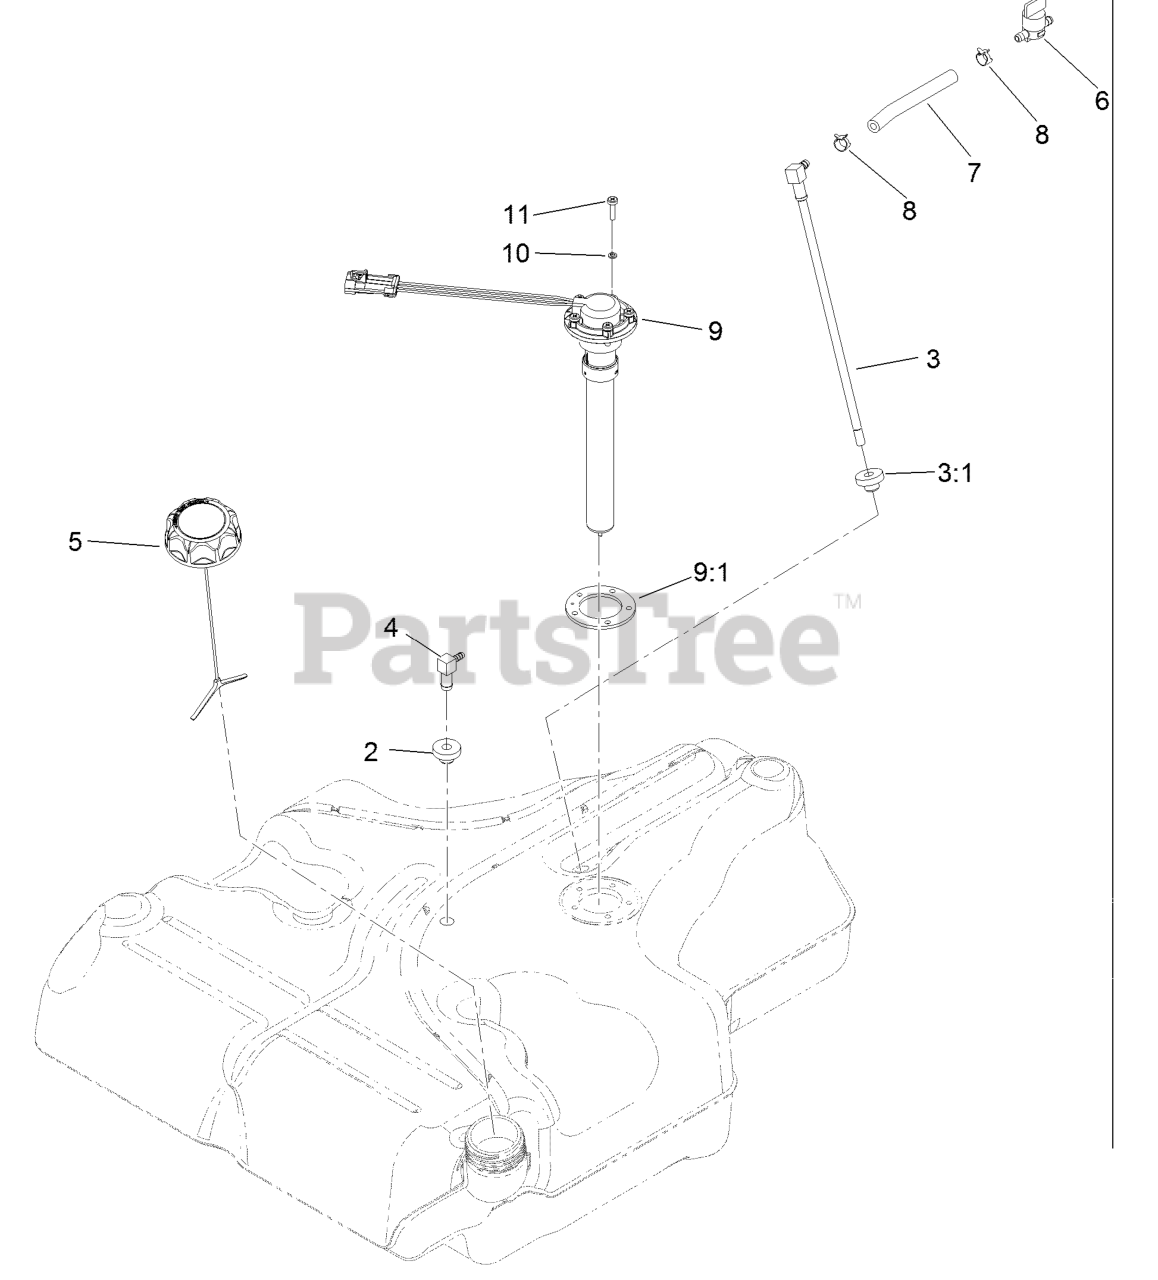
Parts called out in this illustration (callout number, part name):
2	BUSHING
3	FUEL LINE KIT (WITH GROMMET)
3:1	BUSHING
4	FITTING-90 ELBOW
6	VALVE-FUEL
7	HOSE-FUEL
8	CLAMP-HOSE
9:1	GASKET-SENDER, FUEL
10	WASHER-LOCK
11	SCREW-PAN
